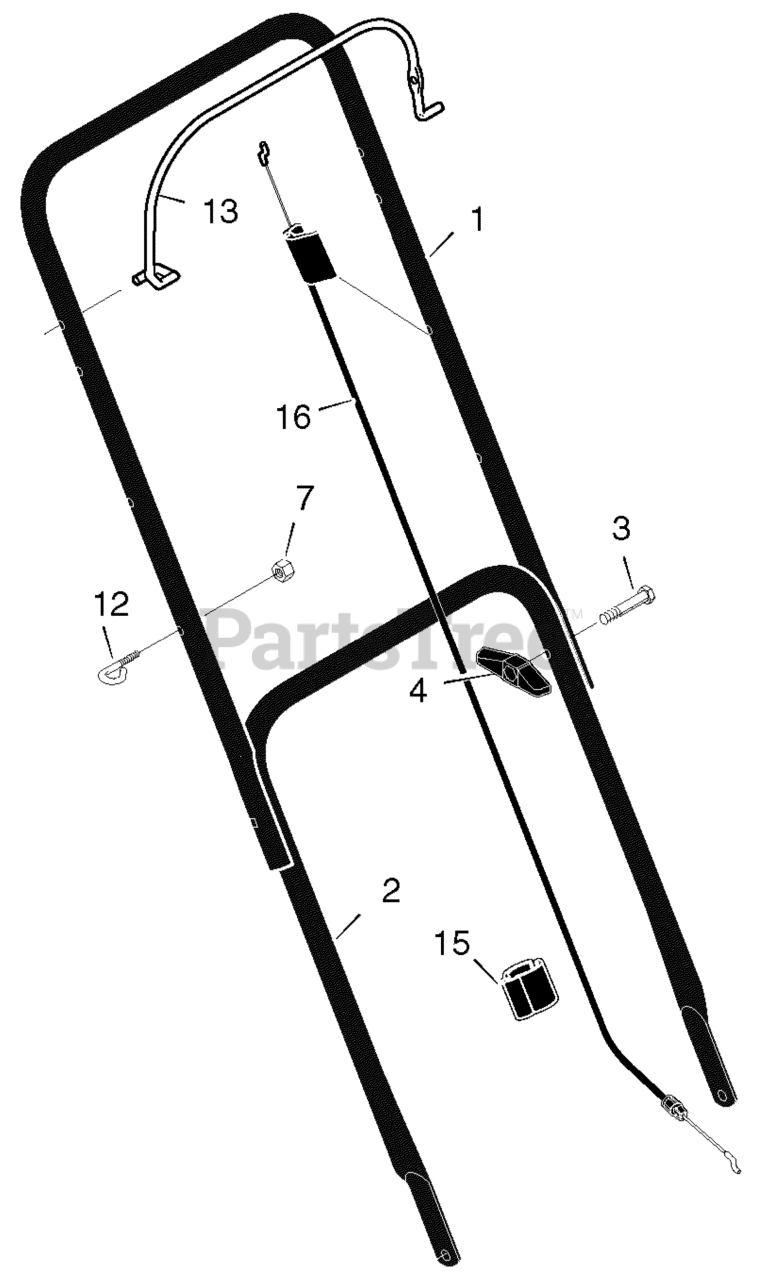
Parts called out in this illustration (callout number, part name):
1	Handle, Upper (Black)
1	Handle, Upper (Gray)
2	Handle, Lower (Black)
2	Handle, Lower (Gray)
4	Knob, Plastic
7	Locknut
12	Guide, Rope
13	Engine Stop Lever
15	Fastener, Cable
16	Engine Stop Cable *
